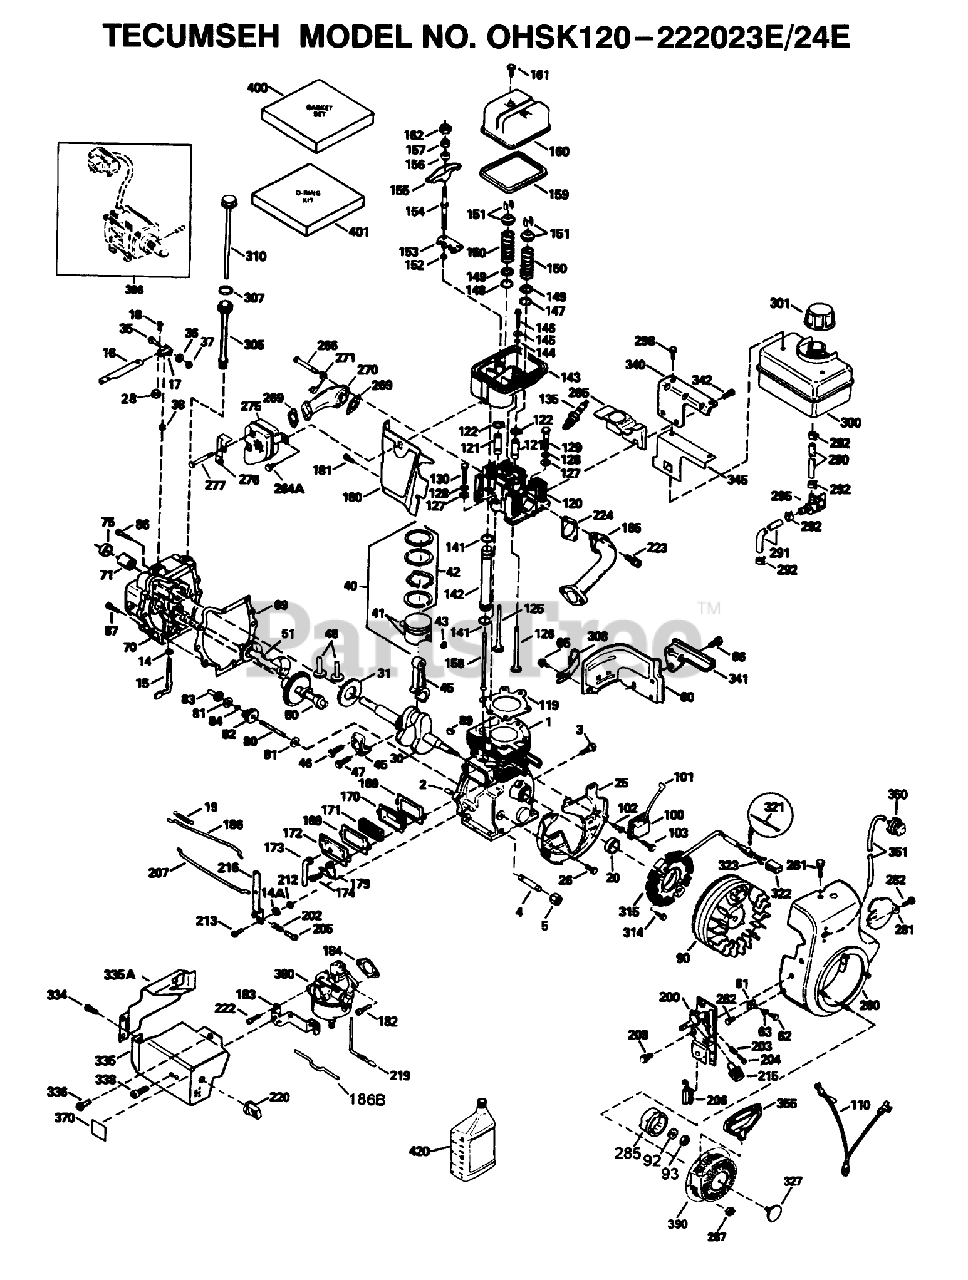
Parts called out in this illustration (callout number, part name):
1	Cylinder (Incl. Ref.#2, 20, 72 80)
2	Pin-Dowel
3	Screw (1/4-20x1/2)
4	Nipple-Pipe
5	Cap-Pipe
14	Washer-Flat
14A	Washer
15	Rod-Governor (Incl. Ref.#14 38)
16	Governor Lever
17	Clamp-Lever, Governor
18	Screw
19	Throttle Spring
20	Seal-Oil
25	Baffle-Housing, Blower
26	Screw (1/4-20x19/32)
28	Nut-Lock
30	Crankshaft
31	Counterbalance Gear
35	Screw
36	Washer-Lock
37	Nut-Lock
38	Ring-Retaining
40	Piston, Pin Ring Assy. Std.(Includes ref. #41, 42 43)
41	Piston Pin Assembly Standard (Includes ref. #43)
42	Ring Set (STD)
43	Retaining Ring-Piston Pin
45	Rod Assembly-Connecting (Incl. ref. #46, 47 49)
46	Bolt-Rod
47	Bolt-Rod
48	Lifter-Valve
50	Camshaft
51	Counterbalance Weight
60	Extension-Housing, Blower
61	Bracket
62	Screw (8-32 x 3/8)
63	Grommet
65	Screw
66	Screw (1/4-20x19/32)
69	55072/75/86/89 TWO
70	Cylinder Cover (Incl. Ref. #14, 15, 38, 71, 75)
71	2025A77 WIZARD ROTA
75	Seal-Oil
80	Governor Shaft
81	Washer
82	Gear-Asm Governor
83	Governor Spool
84	Ring-Retaining
86	Screw (1/4-20x1-3/16)
87	Screw (1/4-20x1-11/16)
89	Key-Flywheel
90	Flywheel (W/Ring Gear)
93	Nut-Flywheel
100	Solid State ASM
101	Cover-Spark Plug
103	Screw (T-15, 10-24 x 15/16)
110	Ground Wire
119	Cylinder Head Gasket
120	Cylinder Head
121	Valve Guide Kit (Incl. Ref.# 2 of 122)
122	Ring-Retaining
125	Exhaust Valve (Std.)
126	Intake Valve (Std.)
127	Washer-Flat
128	Washer-Belleville
129	Screw
130	Screw
135	Spark-Plug (RL86C)
141	ORing
142	Push Rod Tube
143	55062 SNWTHWR ADN.W
144	ORing
145	Washer
146	Bolt-Rod, Connecting
147	ORing
148	ORing
149	Cap-Valve Spring
150	Spring-Valve
151	Keeper-Spring, Valve
152	ORing
153	Guide-Push Rod
154	Rocker Arm Stud
155	Arm-Rocker
156	Bearing-Rocker Arm
158	Rod-Push
159	ORing
160	Housing-Rocker Arm
161	Screw
162	Jam Nut
169	Gasket-Cover, Valve
170	Body-Breather
171	Element-Breather
172	Cover-Valve
173	Tube-Breather
174	Screw
179	Retainer Clip
180	Blower Housing Extension
181	Screw
182	Screw (T-30, 1/4-20 X 27-32)
183	Bracket-Choke
184	Gasket-Carburetor To Intake Pipe
185	Intake Pipe
186	Governor Link
186B	Spring-Choke
192	Washer-Belleville
200	Bracket-Control (Incl. Ref. #203, 204 and 206)
202	Compression Spring
203	Spring-Compression
204	Screw
205	Screw
206	Terminal
207	Choke Link
209	Screw (10-32 x 1/2)
212	Bushing
213	Screw
215	Knob-Control
216	Lever-Adjusting
219	Rod-Choke
220	Knob-Control
222	Screw (10-32 x 1/2)
223	Screw (T-30, 5/16-18 X 7/8)
224	Gasket-Pipe
260	Blower Housing
261	Screw
262	Screw
264A	Screw
265	Cover-Cylinder Head
266	Screw (5/16-18 X 1-9/32)
269	Gasket-Manifold, Exhaust
270	Exhaust Manifold
271	Plate-Locking
275	Muffler
276	Plate-Locking
277	Screw (5/16-18 X 4-1/2)
281	Screw
282	Screw (8-32 x 3/8)
285	Cup-Starter
287	Nut and Lock Washer (1/4-28)
290	Line-Fuel
291	Line-Fuel (8.62)
292	Clamp-Line, Fuel
295	Valve-Shut Off, Fuel
298	Screw (1/4-15x7/8)
300	Tank-Fuel (Incl. Ref. #292 301)
301	Cap-Fuel
305	Tube-Fill, Oil
307	O-Ring
308	Clip-Tube, Fill
310	Dipstick
314	Screw (1/4-20 x 3/4)
315	Alternator Coil (3/5)(Incl. 321-323)
315	Coil-Alternator, 18 Watt (Includes 323)
321	Diode
322	Body-Connector
323	Terminal
327	Plug Starter
334	Screw (8-32 X 5/16)
335	Carburetor Cover
335A	Carburetor Cover
336	Screw (10-32x1/2)
338	Screw (10-32 x 1/2)
340	55073/76/87/90 SNWT
341	Bracket-Fuel Tank
342	Screw (5/16-18 X 7/8)
345	Baffle-Heat
350	Primer-Asm
351	Line-Primer
355	Handle-Starter, Mitten Grip
370	Decal-Lubrication
380	Carburetor (Incl. Ref. #184)
390	Starter-Rewind
396	Starter-Electric (110 Volt)
400	Gasket Set
401	O-Ring Kit
420	Oil-Engine (SAE 5W30)
